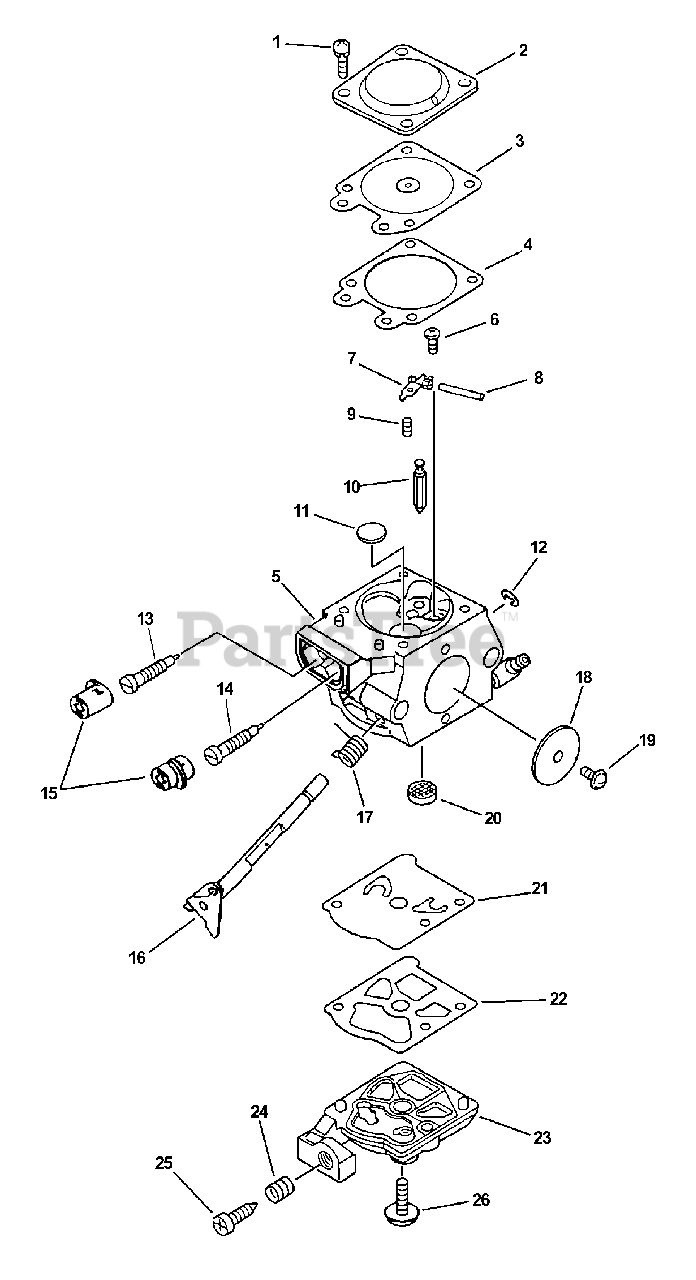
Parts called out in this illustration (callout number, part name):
2	COVER, METERING
3	DIAPHRAGM, METERING
4	GASKET, METERING
5	BODY, CARBURETOR
6	SCREW, METERING LEVER PIN
7	LEVER, METERING
8	PIN, METERING LEVER
9	SPRING, METERING LEVER
10	VALVE, INLET NEEDLE
11	PLUG, WELCH
12	RING, RETAINING
13	NEEDLE - MIXTURE
14	NEEDLE - MIXTURE
15	CAP, LIMITER
16	SPRING, THROTTLE RETURN
17	SPRING, THROTTLE RETURN
18	VALVE, THROTTLE
20	STRAINER
21	DIAPHRAGM, PURGE
22	GASKET, PURGE
23	COVER, PUMP
24	SPRING, IDLE ADJUST
25	SCREW, IDLE ADJUST
26	SCREW, PUMP COVER
26	REPAIR KIT
26	DIAPHRAGM/GASKET KIT
